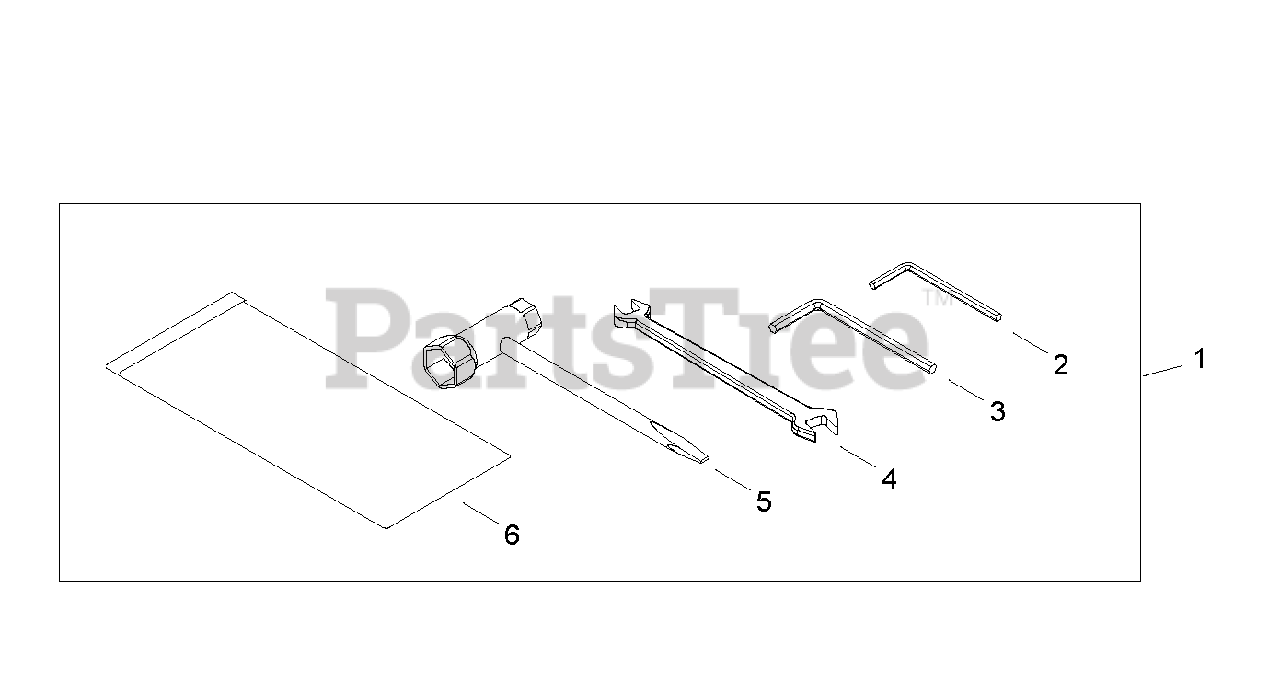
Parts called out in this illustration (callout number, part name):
1	TOOL KIT
2	HEX KEY - 4mm
3	HEX KEY - 6mm
4	SPANNER - 8X10mm
5	T-WRENCH - 13X16mm
6	BAG, TOOL
